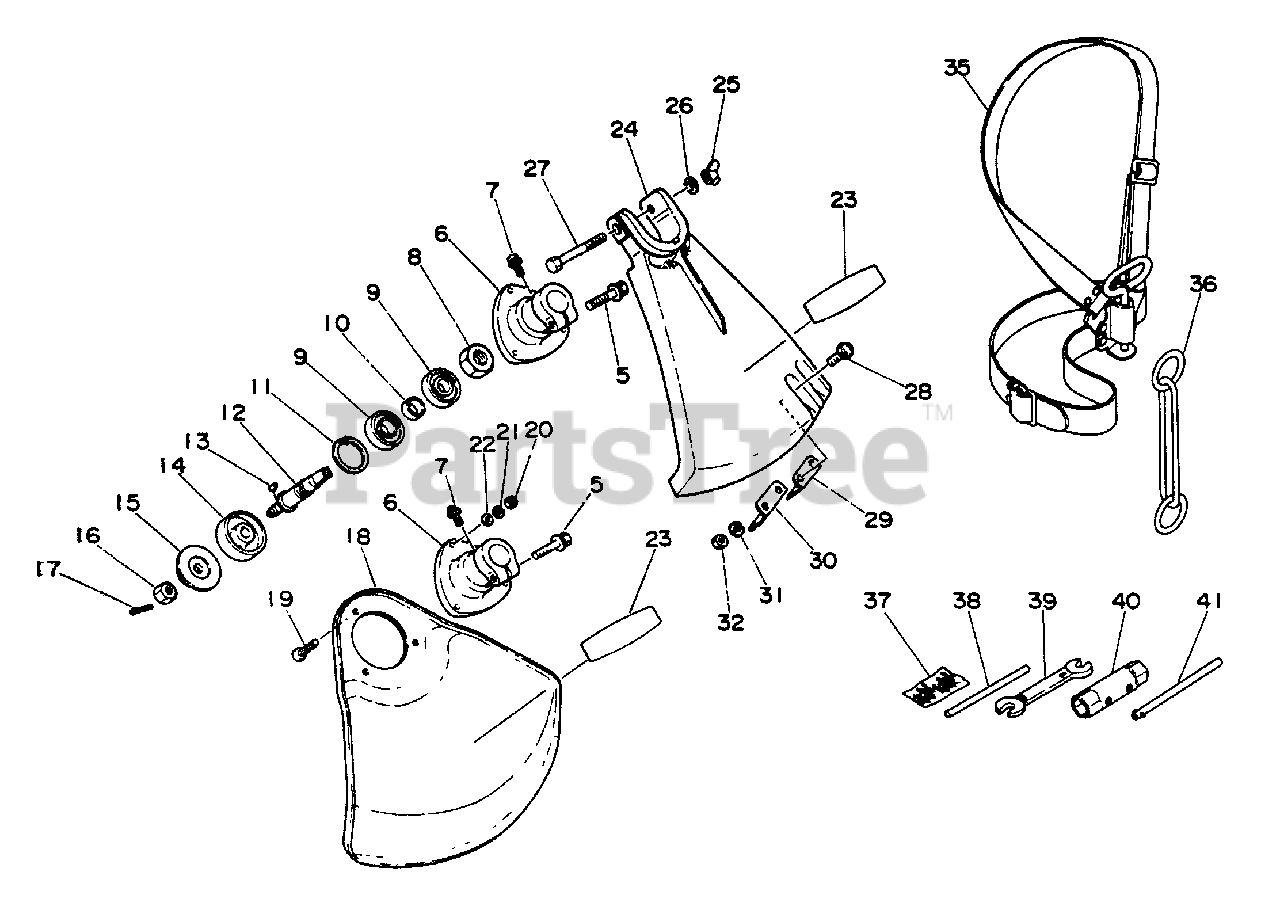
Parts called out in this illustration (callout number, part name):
5	BOLT - 5×25
6	CASE, BEARING
7	SCREW 4×10
8	NUT 12 L.H.
9	BEARING, BALL 6001 DDU
11	RING, SNAP 28
12	GEAR, SHAFT
14	PLATE, ADAPTER - UPPER
15	PLATE, ADAPTER - LOWER
17	PIN, COTTER 2×22
18	SHIELD ASS'Y (STEEL)
19	SCREW 4×18
21	WASHER, SPRING 4 MM
22	WASHER 4 MM
23	LABEL - ECHO
24	SHIELD - PLASTIC
25	NUT, WING 6
26	WASHER 6.5×11.5×0.8
27	BOLT - 6×50
28	SCREW 5×14
29	KNIFE, TRIMMER LINE
31	WASHER, SPRING 5
32	NUT M5
35	SHOULDER STRAP ASSY
36	HOOK
37	PIN, COTTER 2×22 (PKG. OF 10)
38	ROD, LOCKING
39	SPANNER 8×10
40	WRENCH 17×19
41	ROD, HANDLE
